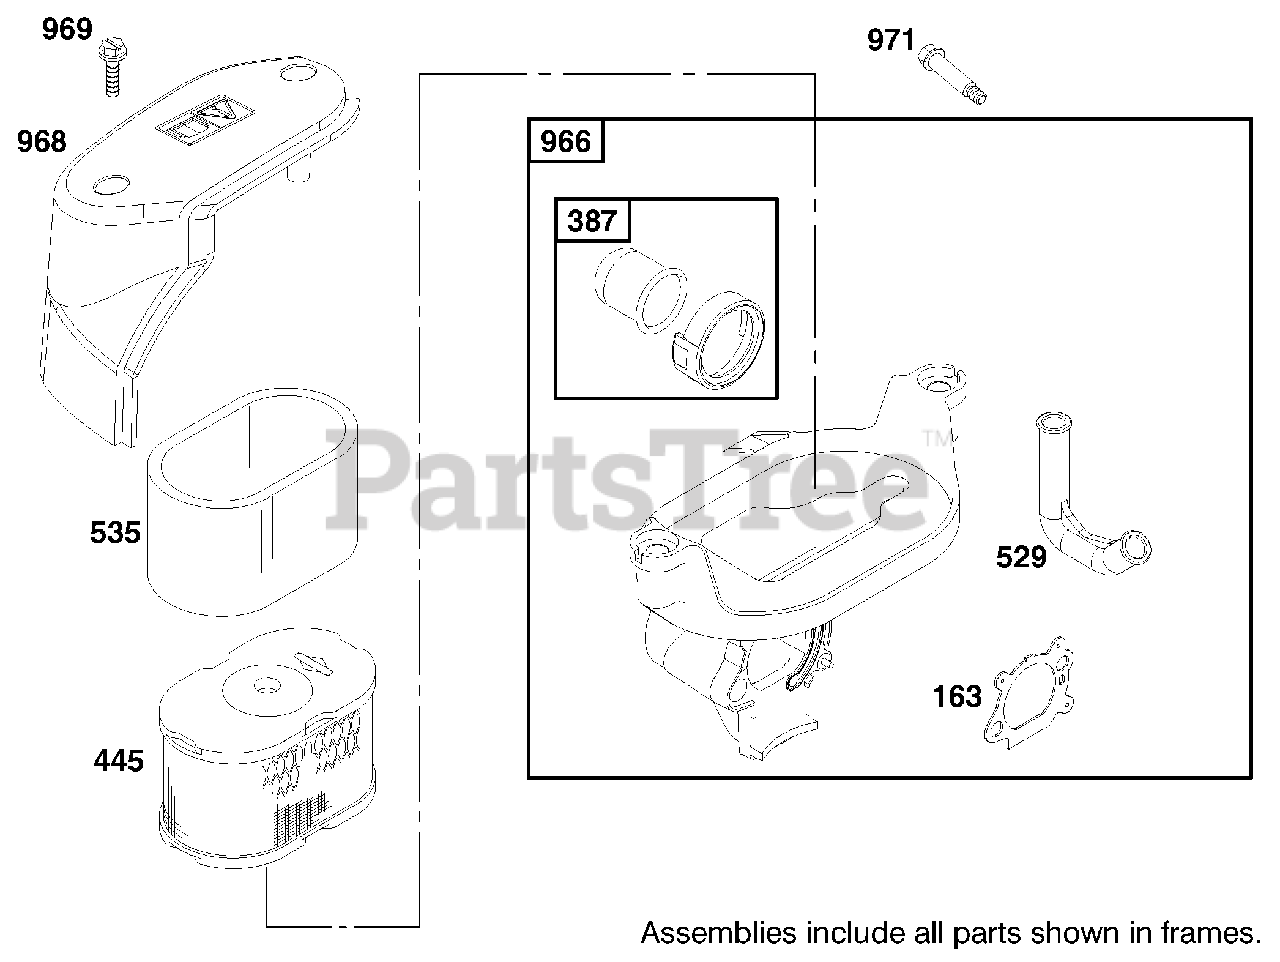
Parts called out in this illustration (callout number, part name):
163	Gasket-Air Cleaner
387	Primer-Carburetor
445	Filter-Air
529	Grommet-Breather
535	Filter-Air
966	Base-Air Cleaner
968	Cover-Air Cleaner
969	Screw-Cover Mtg.
971	Screw-Air Cleaner
